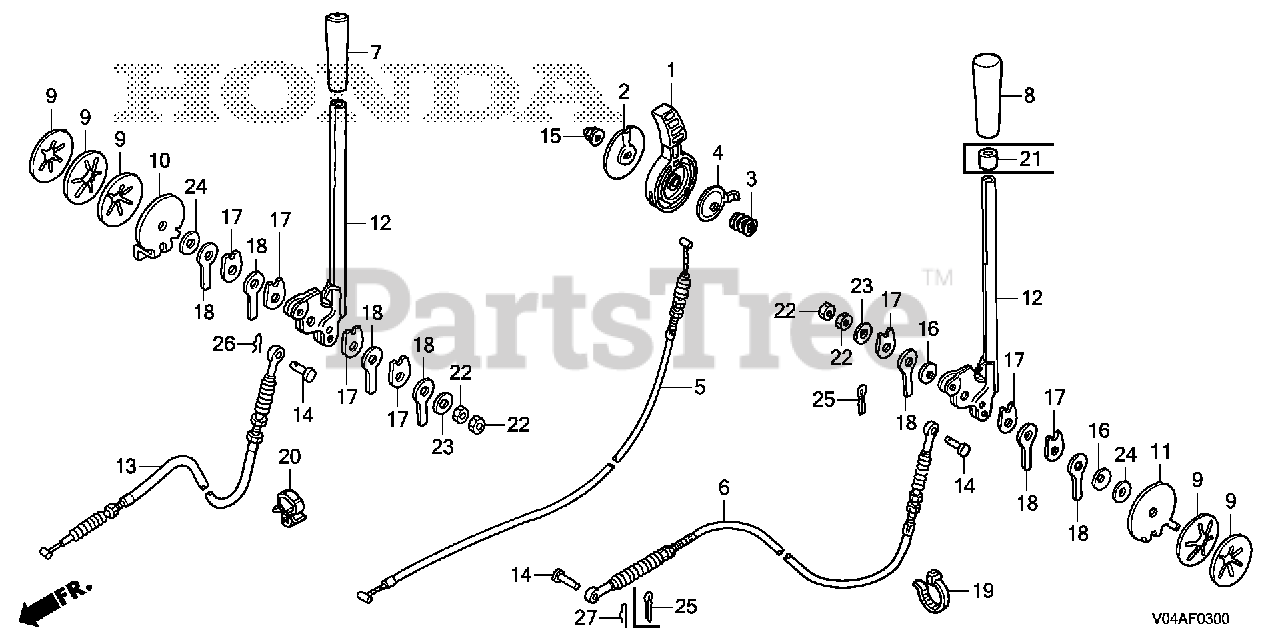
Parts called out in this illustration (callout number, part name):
1	LEVER, THROTTLE
2	PLATE, THROTTLE LEVER
3	SPRING, THROTTLE LEVER
4	SEAT, SPRING
5	CABLE, THROTTLE
6	CABLE, CHANGE
7	GRIP, CHANGE LEVER
8	GRIP, CHANGE LEVER
9	SPRING, ADJUSTING ARM
10	PLATE, R. STOPPER
11	PLATE, L. STOPPER
12	LEVER, CHANGE
13	CABLE, CHUTE GUIDE
14	PIN, CONTROL BOX SETTING
15	NUT, CAP (6MM)
16	WASHER, LOCK
17	WASHER, FRICTION
18	WASHER, FRICTION SETTING
19	BAND, SUCTION HOSE (BLACK)
20	CLAMP, CABLE
22	NUT, HEX. (8MM)
23	WASHER, PLAIN (8MM)
24	WASHER, PLAIN (8MM)
25	PIN, SPLIT (2.0X12)
26	PIN, LOCK (6MM)
